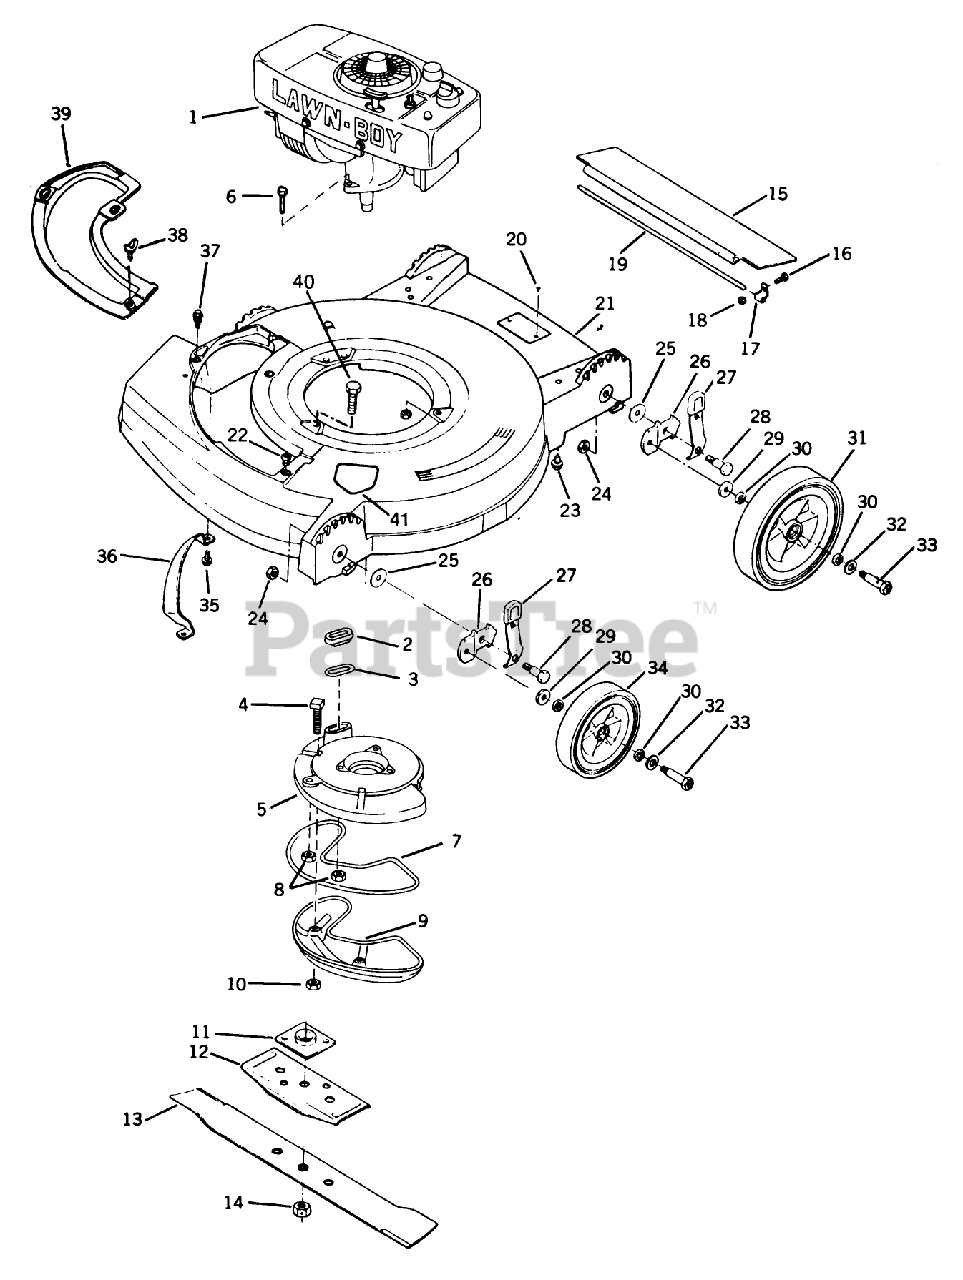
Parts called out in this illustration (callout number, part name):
1	Engine-Complete
3	GASKET S
8	NUT-LOCK F
11	PLATE AND COLLAR ASM
14	NUT-BLADE
17	CLAMP ROD KMC
18	LOCKNUT E
19	ROD T/SHIELD ADV WIRE
24	LOCKNUT
29	WASHER WROUGHT
33	BOLT WHEEL
34	WHEEL & TIRE KIT
36	TOE BAR 19"
38	WING SCREW LAWRE
